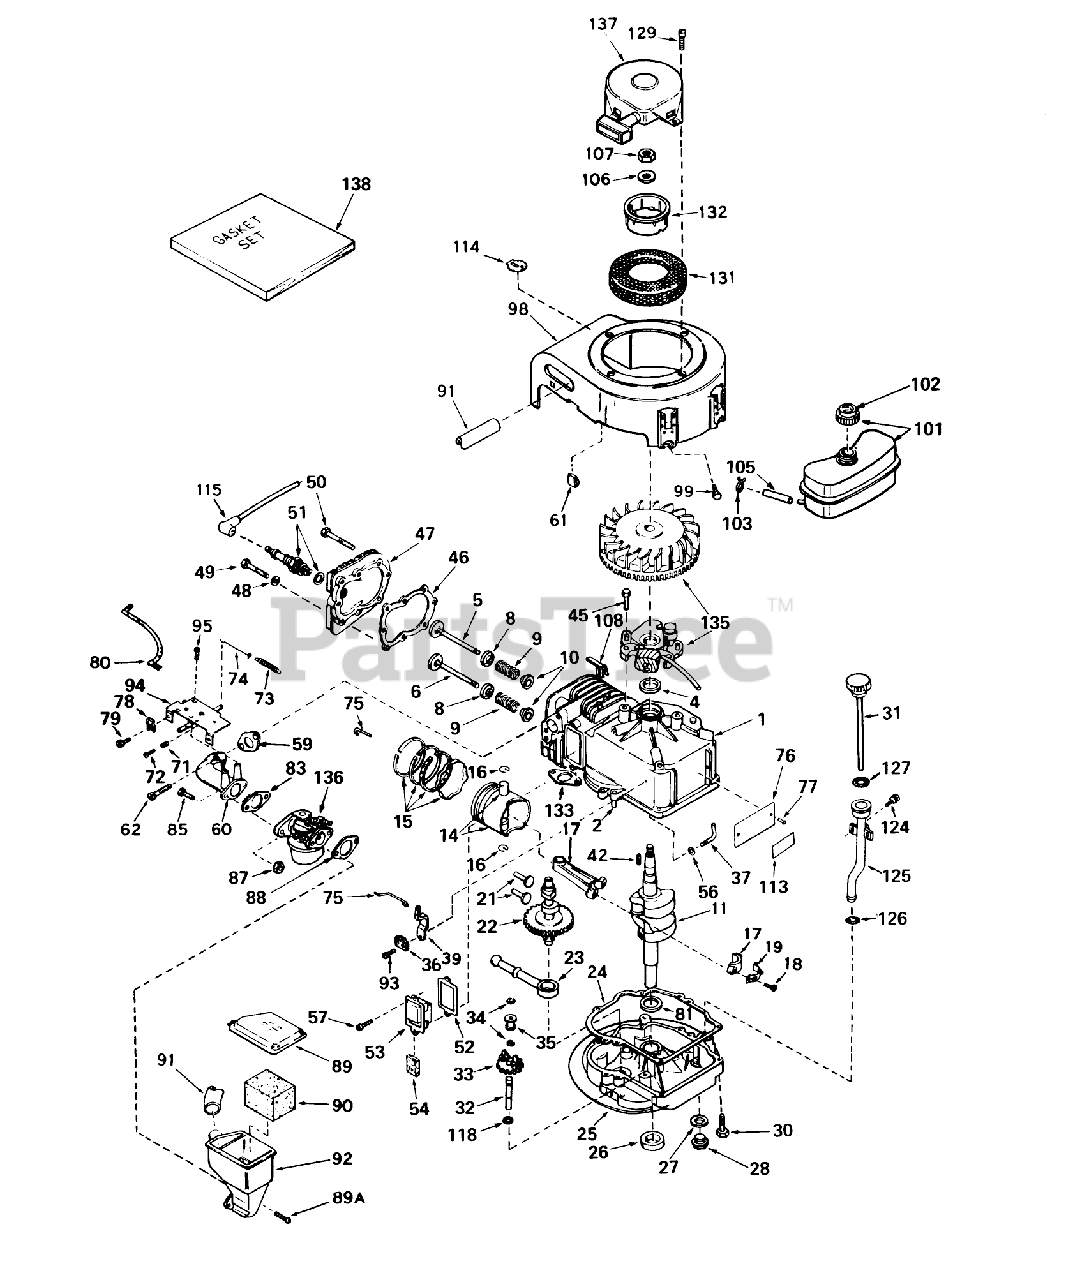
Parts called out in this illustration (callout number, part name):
1	Cylinder Assy. (Incl. Nos. 2 4)
2	Pin-Dowel
4	Seal-Oil
5	Valve, Intake (Incl. Ref. #38, 39 40) (Std.)
5	Valve, Exhaust (1/32" Oversize) (Incl. Nos. 8, 9 10)
6	Valve, Exhaust (Standard) (Incl. Nos. 8, 9 10)
6	Valve, Exhaust (1/32" Oversize) (Incl. Nos. 8, 9 10)
8	Cap-Upper Valve Spring
9	Spring-Valve
10	Cap-Valve, Spring
11	Crankshaft
14	Piston Pin Assembly (Incl. 2 of No. 14) (.010 Oversize)
14	Piston Pin Assembly (Incl. 2 of No. 14) (.020 Oversize)
15	Ring Set Piston (Std.)
15	Ring Set Piston (.010 Oversize)
15	Ring Set Piston (.020 Oversize)
16	Ring-Retaining, Piston Pin
17	Rod Assembly, Connecting (Incl. Nos. 17 18)
18	Connecting Rod Bolt
19	Plate Lock
21	Lifter-Valve
22	Camshaft (Compression Release
23	Oil Pump ASM
24	Gasket, Mounting
25	Flange Assy., Mounting (Incl. Nos. 26, 27, 28 32)
26	Seal-Oil
27	Gasket-Oil Drain
28	Plug Oil Drain
30	Screw (1/4-20 x 1-1/4)
31	Dipstick, Oil
32	Shaft-Governor
33	Governor Gear ASM
34	Ring-Retaining
35	Spool-Governor
36	Clamp-Lever, Governor
37	Rod, Governor (Incl. No. 36)
39	Governor Lever
42	Key Flywheel
45	Screw
46	63573 GIL 42 SNWTHW
47	Head Cylinder
48	Washer
49	Screw
50	Screw Hex Hd. Cap
51	Plug, Spark (J17LM or equiv.)
52	Gasket Breather
53	Breather Assembly (Incl. Nos. 52 84)
54	Element-Breather
56	Washer-Flat
57	Screw
59	Gasket, Intake
60	Pipe, Intake
61	51004 GIL ROTARY TI
62	Screw (1/4-20 x 1)
71	Spring-Compression
72	Screw
73	Spring, Governor
74	Link-Governor
75	Link Governor
76	IDENTIFICATION PLATE
77	Stud
78	Conduit
79	Screw (10-32 x 3/8)
80	Wire, Ground
81	Washer-Thrust
83	Gasket
87	Nut and Lock Washer (1/4-28)
88	Gasket-Air Cleaner
89	Cover, Air Cleaner
89A	Screw, Fil. Hd. Sems
90	Element, Air Cleaner
91	Tube, Air Cleaner
92	Body, Air Cleaner
93	Screw
94	51089 SUPP TO MANUA
95	Screw (10-24 x 9/16)
98	Housing, Blower
99	Screw (1/4-20x19/32)
101	Tank Assy., Fuel (Incl. No. 102)
102	Cap, Fuel
103	Clamp-Line, Fuel
105	Line-Fuel (8.62)
106	Washer
107	Hex Nut
108	Clip-Wire
113	480B GIL SNWTHWR O/
114	8HP RID. W/ELE STAR
115	Cover-Spark Plug
118	Washer-Flat
124	Screw (10-32 x 1/2)
125	Tube Assy., Oil Fill
126	O-Ring
127	O-Ring
129	Screw
131	Screen, Air
132	Starter Cup
133	Gasket Exhaust
135	LEVER
136	Carburetor
137	Starter, Rewind
138	Gasket Set
